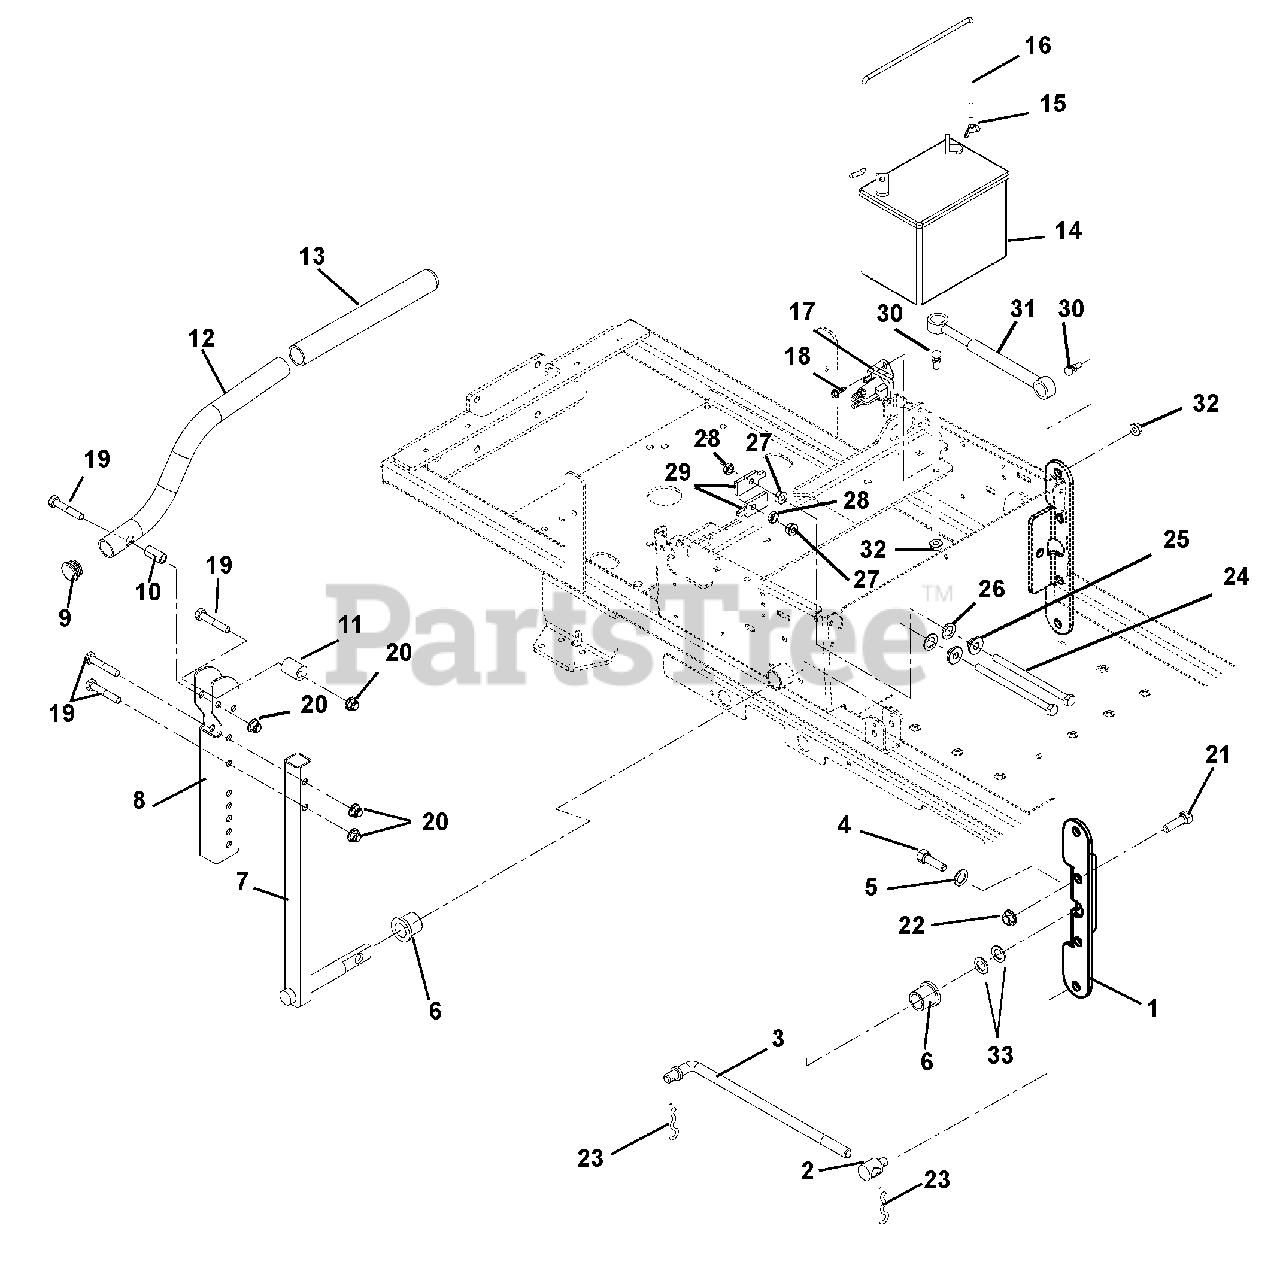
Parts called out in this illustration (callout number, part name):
1	LINK, CONTROL
2	PIVOT, ROD (TRUNNION ) .50
3	LINK,WIREFORM
4	BLT-HEX .38-16X1.0 GR8 YZ EP30
5	WSHR-FL-STL .390X1.5X.125 YWZC
6	BUSHING-1"X.75"X1"
7	WMT, CONTROL ARM (ZOOM)
8	CHANNEL, UPPER HANDLEBAR
9	CAPLUG, HANDLEBAR
10	BSHG, SPCR .330X.500X1.01 PM
11	BSHG,ECCEN .328X.750X1.01 PM
12	HANDLE BAR
13	GRIP - HANDLEBAR
14	Battery, Exide Sealed Maintenance Free U1-250 (Purchase replacement locally)
15	NUT-LK WING .250-20 YWZC
16	BATTERY ROD
17	SOLENOID, HP RTV
18	@SCR-TAP .25-20X.37 HWH YWZ TR
19	@BLT-HEX .31-18X1.75 GR5 YWZC
20	@NUT-LK-NYL-FLG .31-18 YWZC
21	@BLT-HEX .38-16X1.25 GR5 YWZC
22	NUT-HEX-JAM .375-16 YWZC
23	PIN-HAIR INT .08X.18X1.18 YWZC
24	BLT-HEX,5/16-18X5 G2 HH YWZC
25	BSHG-FLG .32X.500X.344X.880
26	WSHR-FL-STL .52X.827X.062 YWZC
27	@NUT-SPNLK-FLG .312-18 YWZC
28	NUT- JAM .312-18 YWZC
29	STOP TAB
30	STUD- BALL
31	DAMPER, CONTROL
32	@NUT-LK-TOP-FLG .31-18 YWZC
33	WSHR-FL-STL .755X1.25X.125 YZ
